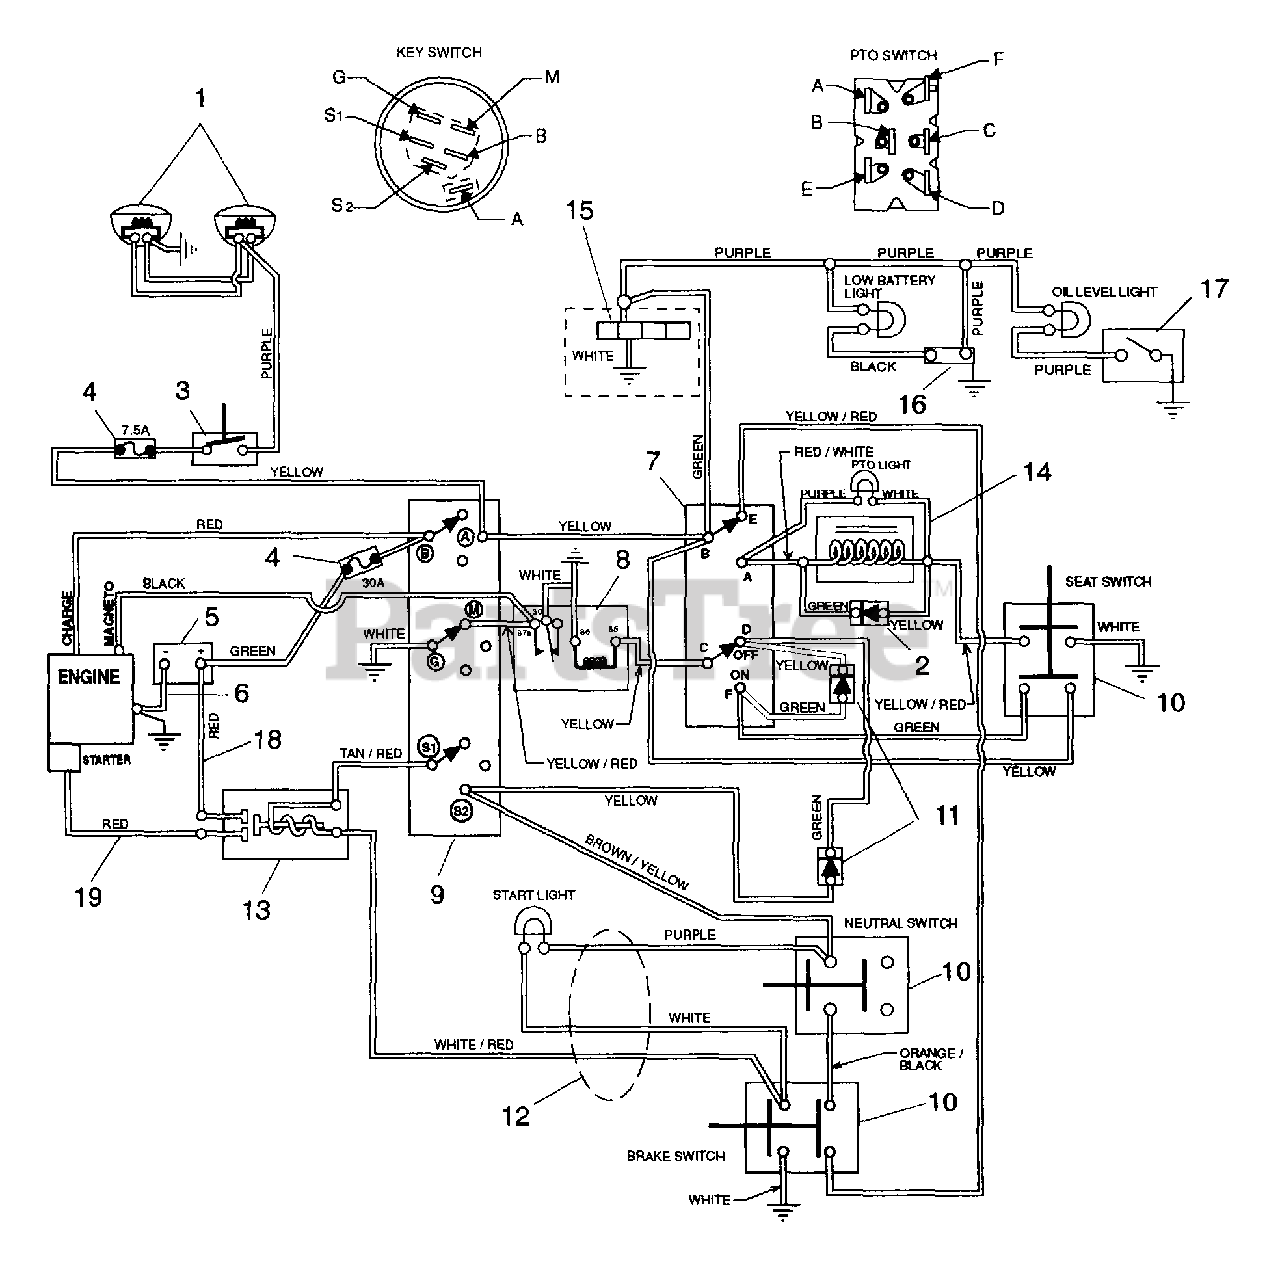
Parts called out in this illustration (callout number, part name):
1	HEADLIGHT- L.H.
1	HEADLIGHT- R.H.
2	DIODE & HOUSING
3	LIGHT SWITCH
4	7.5 Amp Fuse
4	30 Amp Fuse
5	BATTERY W/TUBE
6	GROUND CABLE .31X22.00X.31
7	SWITCH ASSEMBLY- PTO
8	RELAY
9	KEY SWITCH
10	SWITCH- DOUBLE POLE N.O./N.O.
11	MOLDED DIODE PLUG 1 AMP
12	WIRE HARNESS- YT15/16.5
13	SOLENOID
14	ELECTRIC CLUTCH/BRAKE (3.4AMP)
15	HOURMETER
16	VOLTAGE SENSOR
17	OIL SENSOR- FASCO #0454-0513
18	START CABLE 22"
19	STARTER CABLE 6.75"
